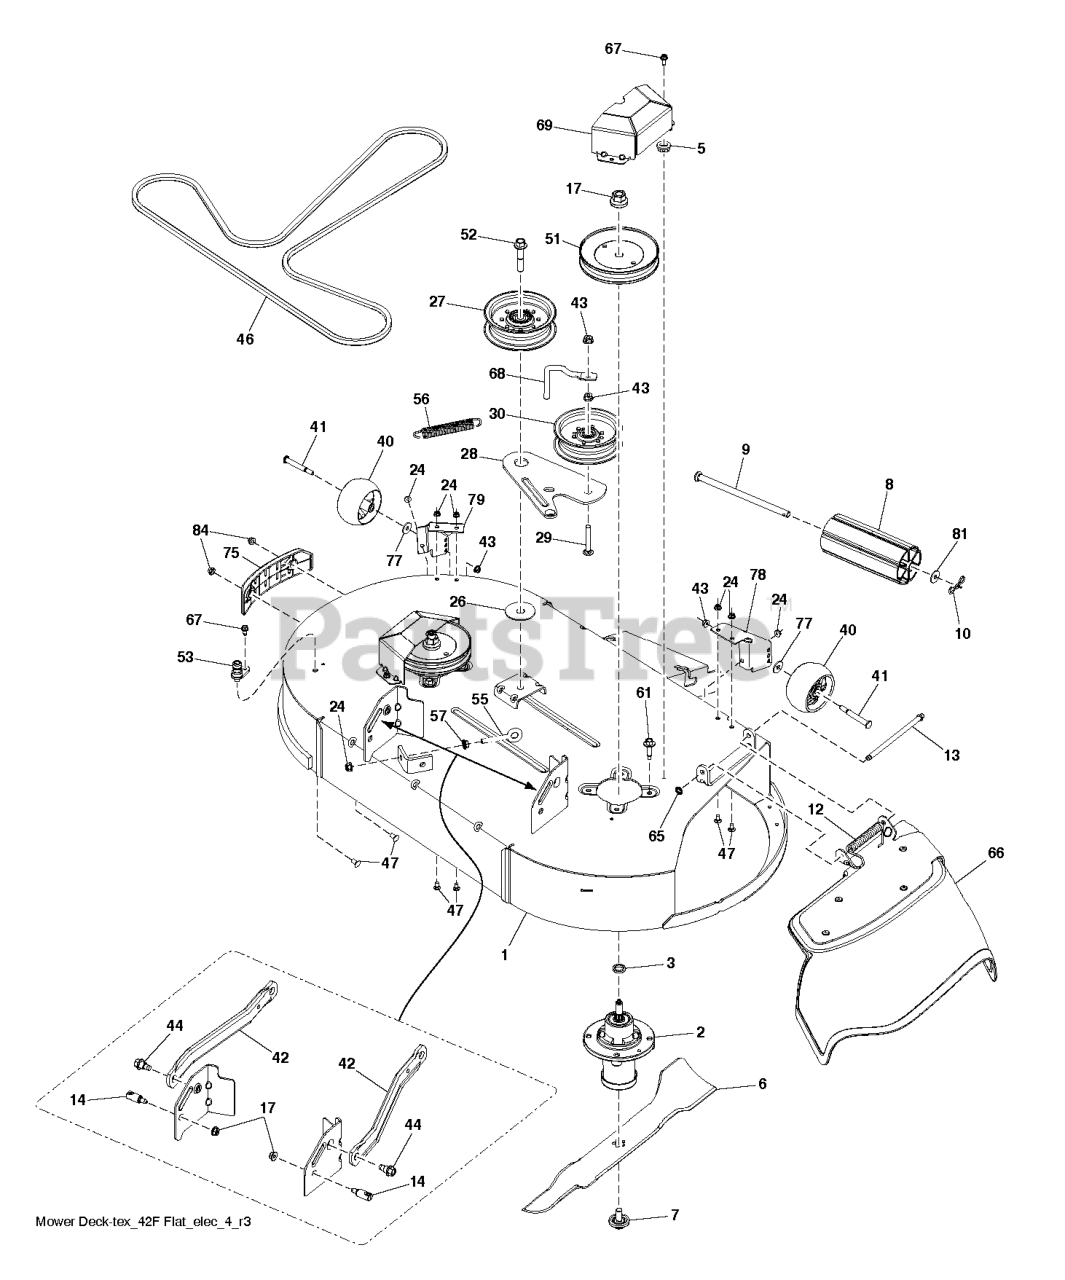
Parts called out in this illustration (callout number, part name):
1	DECK SVC.42F.668
2	MANDREL ASM, CAST IRON
3	WASHER.SPACER.MANDREL
5	NUT.FLANGE.LOCK.TOP
6	BLADE.42.FCS.BAGGING.BLADE.RAW
7	BOLT.WASHER.ASM.7/16-2
8	NOSE ROLLER 48"
9	ROD.ROLLER.NOSE.NARROW.48"
10	PIN.COTTER.5/16.BOW TI
12	SPRING.42.FCS.DEFLECTOR
13	ROD.HINGE
14	STUD.FASTNER.W/ANTI-ROTATE
17	NUT LOCK HEX FLANGE 5/16-18
24	5/16-18 NYLOC FLANGE NUT
27	PULLEY.IDLER.MWR.STATI.LH
28	ARM.42"FCS.CLUTCHING.X431
30	PULLEY.IDLER.2006
40	WHEEL.GAUGE.RALLY
41	BOLT.SHOULDER.3/8-16X3-5/8.
42	ARM.RFIXED.MOWER.SUSPNSIONX431
43	NUT LOCK FLG 3/8-16 UNC
44	BOLT.SHOULDER
46	BELT.42.FCS.TRACTOR.DECK.DRIVE
47	BOLT 5/16C X 3/4" CARRIAGE
51	PULLEY MANDREL 5.0"
52	SCREW.7/16-14 X 2.125.WASHER
53	PORT.WASHOUT
55	EYE BOLT 5/16 X 3.50
56	SPRING.EXTN.42.FCS.TR.DECK.DRV
57	NUT 5/16C WHIZ
61	BOLT.HEX.WASHR.HED.313-18X1.19
65	NUT PUSH M
66	DEFLECTOR.ASM.42.FCS.ORANGE
67	SCREW.1/4-20X5/8
68	KEEPER.BELT.IDLER.54"T
69	COVER.42".MANDREL.FCS.PNT.498
75	BUMPER.42CC.TRIM.SIDE.ASSY.HUS
77	WASHER
78	BRACKET.PNT.GA-WHEEL.FCS.42.RH
79	BRACKET.PNT.GA-WHEEL.42FCS.LH
81	BUSHING.NOSE.ROLLER
84	SHOULDER BOLT 5/16-18TT
